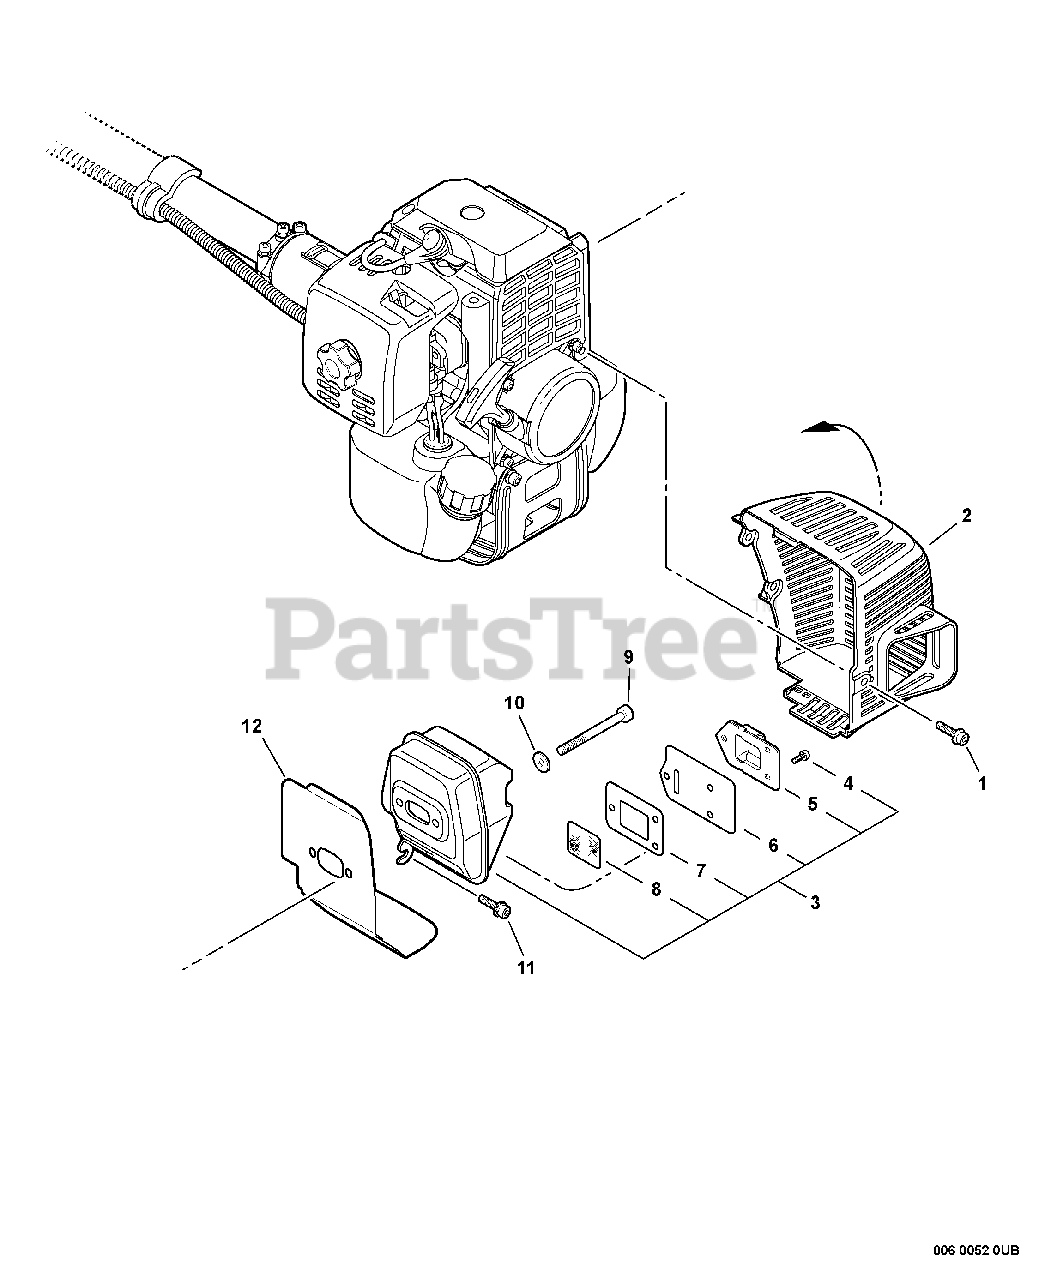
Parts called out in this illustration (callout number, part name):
1	BOLT 5×14
2	COVER, MUFFLER
3	MUFFLER ASSY
4	SCREW 4×12
5	GUIDE, EXHAUST
6	GASKET, EXHAUST
7	GASKET, EXHAUST
8	SCREEN, SPARK ARRESTER
9	BOLT 5×60
10	WASHER, FLAT 5.5×10×0.8
11	BOLT 5×12
13	GASKET, EXHAUST
